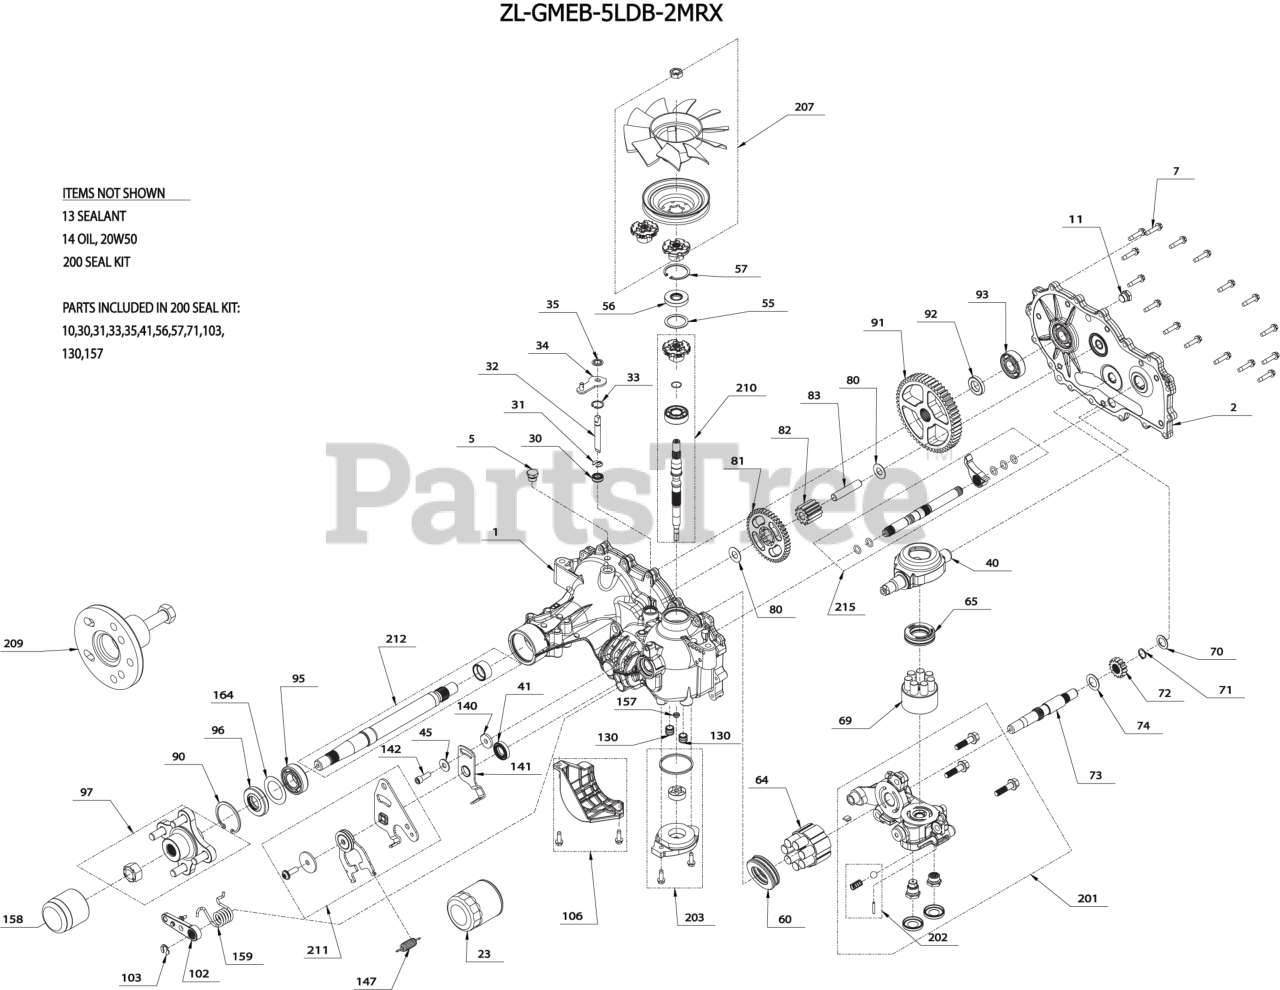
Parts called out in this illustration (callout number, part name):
2	SIDE COVER RH
7	SCREW,HEX WASHER 1/4-20X1.125
11	Plug External Vent
13	SEALANT TUBE 10.1OZ.
14	FLUID, HYDRO 15W50 QT
23	FILTER, HYDRO-GEAR 2800 TRANS
30	Seal, lip .375 x 375 x 325
31	RING. RETAINING
32	ROD, BYPASS
33	RING, RET .750
34	ARM, BYPASS
35	RING, RTNG .
40	TRUNNION, SWASHPLATE
41	SEAL, LIP 18X32X7
45	WASHER
55	WASHER 1.23X1.56X.04
56	SEAL, LIP 17X40X7
57	RING, RET 1.56 INT
60	HG THRUST BEARING (51462)
64	HG 16CC CYLINDER BLOCK (71579)
65	BEARING. THRUST 30 X 52 X 13
69	ASSY, BLOCK 7 PISTON
70	WASHER .63X1.0X.05
71	RING, RET 62 EXT
72	GEAR 14T STEEL
73	SHAFT, MOTOR
74	WASHER .71 X 1.16 X .04
80	WASHER .5X1.0X.032
81	GEAR 45 TOOTH
82	GEAR 11 TOOTH STEEL
83	JACK SHAFT (PIN)
90	RING, RETAINING
91	GEAR 54 TOOTH
92	SPACER
93	KIT, BEARING
95	BEARING, BALL 25.4 X 52 X 15
96	SEAL, LIP
97	KIT, HUB 4 BOLT
102	BRAKE ARM HG 71957
103	CLIP,BRAKE ARM HYDROGEAR 52027
106	KIT FILTER GUARD
130	TUBE CHARGE TRIPLE ORING
141	ARM, NEUTRAL RIGHT
142	SHCS 5/16-24X1 PATCH
147	SPRING, HYDROGEAR P/N 51833
157	KIT GEROTOR SEAL
158	CAP, AXLE
159	SPRING, TORSION CCW
164	WASHER
200	KIT, SEAL
201	KIT, CENTER SECTION RH, CHARGE
202	KIT CHARGE RELIEF
203	KIT, CHARGE
207	KIT, FAN / PULLEY
209	HUB PULLER 5 BLT
210	KIT INPUT SHAFT
211	KIT RTN BIDIRECTIONAL
212	KIT SHAFT AXLE
215	KIT OUTBOARD RH
